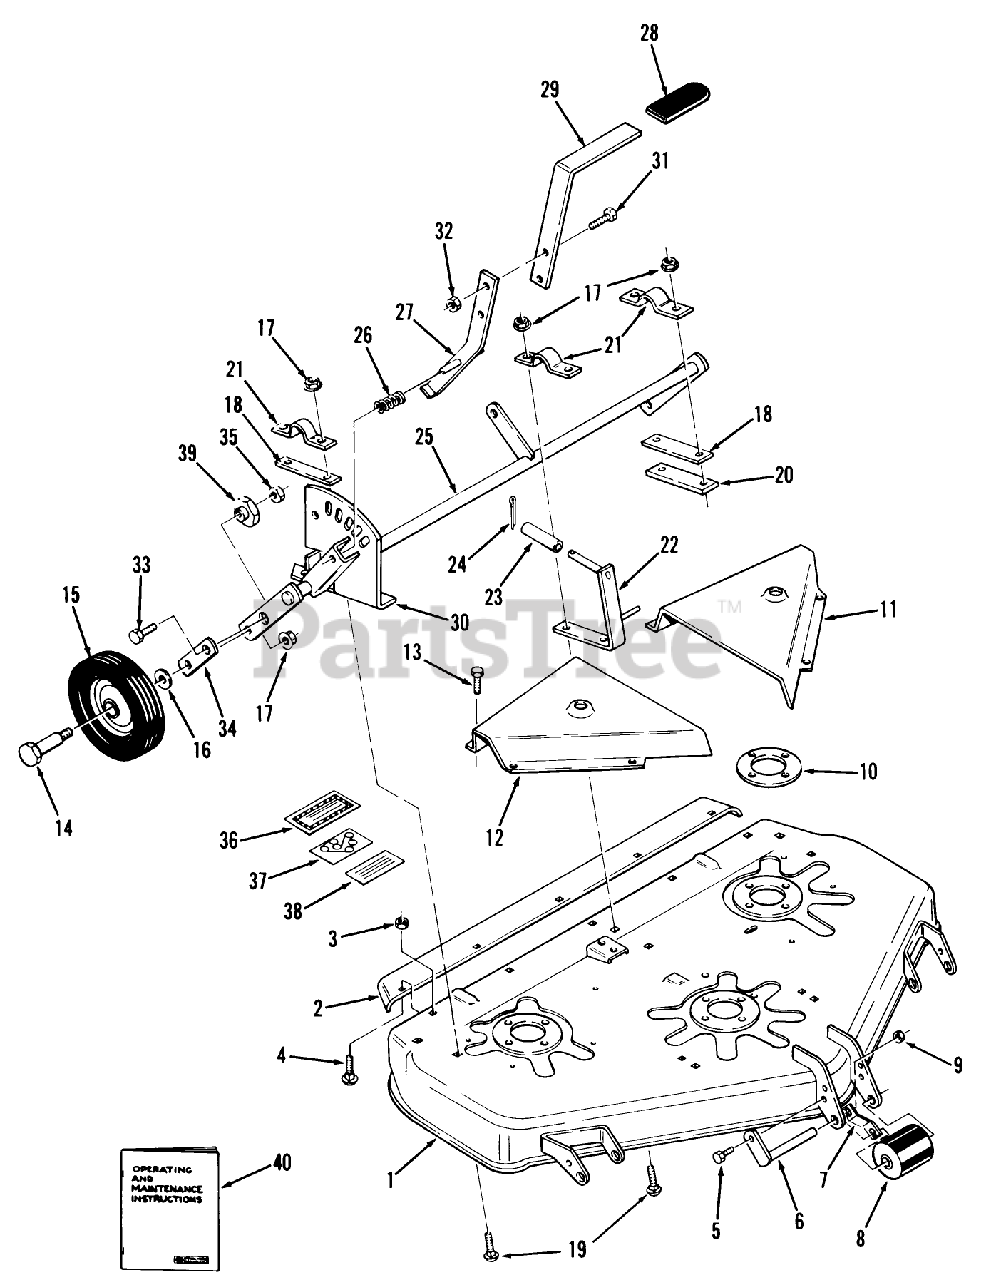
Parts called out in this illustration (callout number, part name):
4	CARRIAGE BOLT -4
10	PLATE-SPINDLE
13	Bolt
14	BOLT-SHOULDER
16	WASHER-FLAT
26	SPRING-COMPRESSION
29	HANDLE-EXTENSION *R
37	DECAL-HEIGHT BELT
40	OperatingandMaintenanceInstructions
